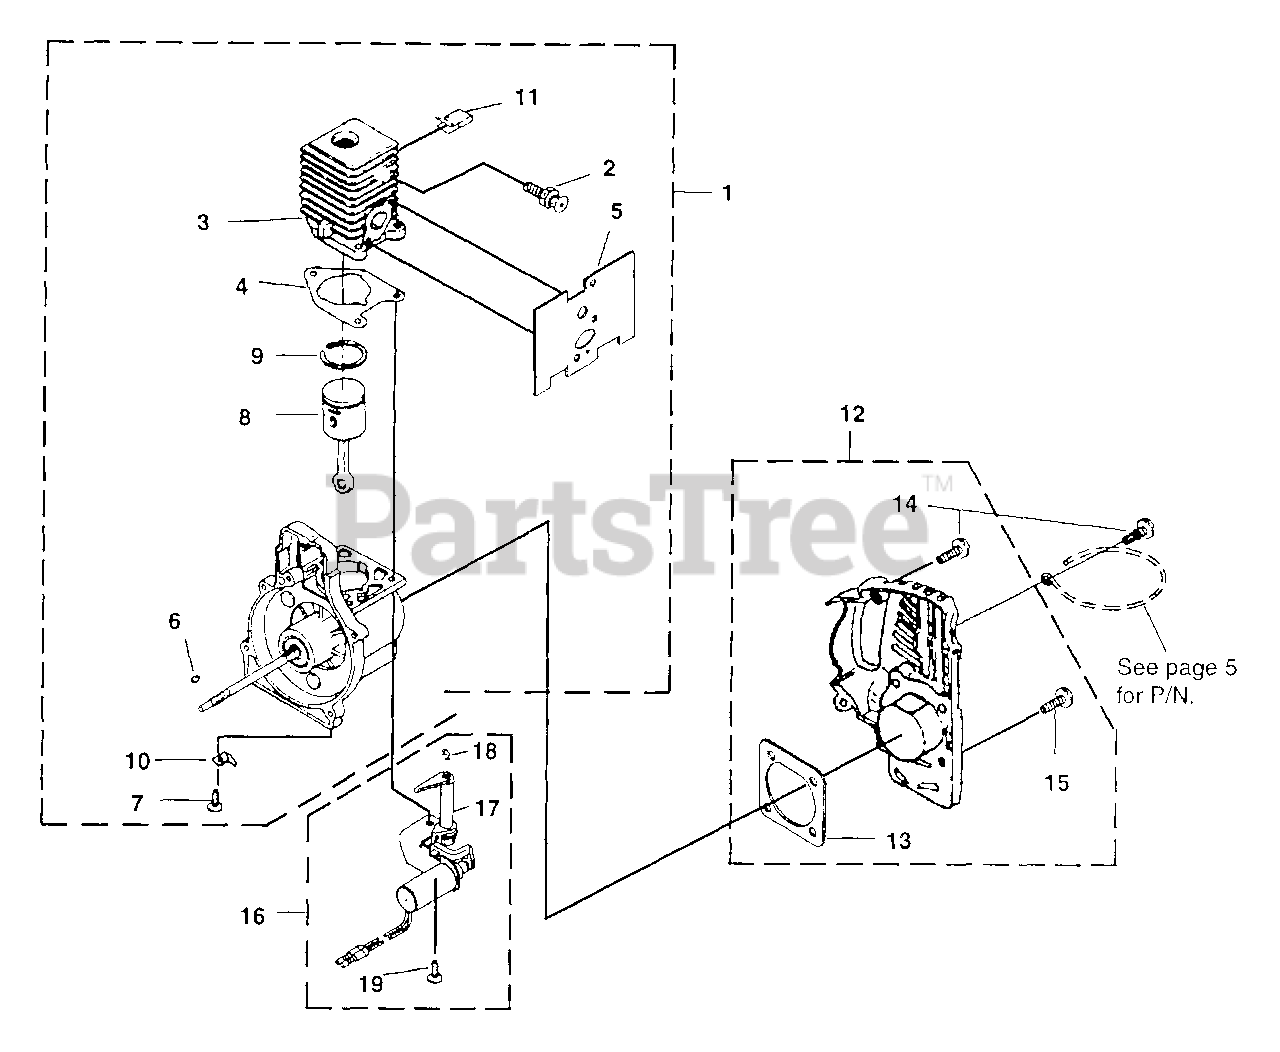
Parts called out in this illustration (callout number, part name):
1	SHORT BLOCK (25CC)
2	COMPRESSION RELEASE VALVE
3	25CC CYLINDER KIT
4	GASKET-Cylinder
5	GASKET-Heat Dam
6	KEY-Woodruff
7	SCREW-Thread Form. (10-24 X 7/8")
8	25CC PISTON & ROD
9	RING-Piston
10	TERMINAL
12	CRANKCASE COVER
13	GASKET-Crankcase Cover
14	SCREW-Plastite (#10 X 3/4")
15	SCREW-Taptite (10-24 X .910)
16	SOLENOID ASSEMBLY
17	ARM-Lever
18	RING-Retaining
19	SCREW-Thread Form (10-24 x 7/8")
